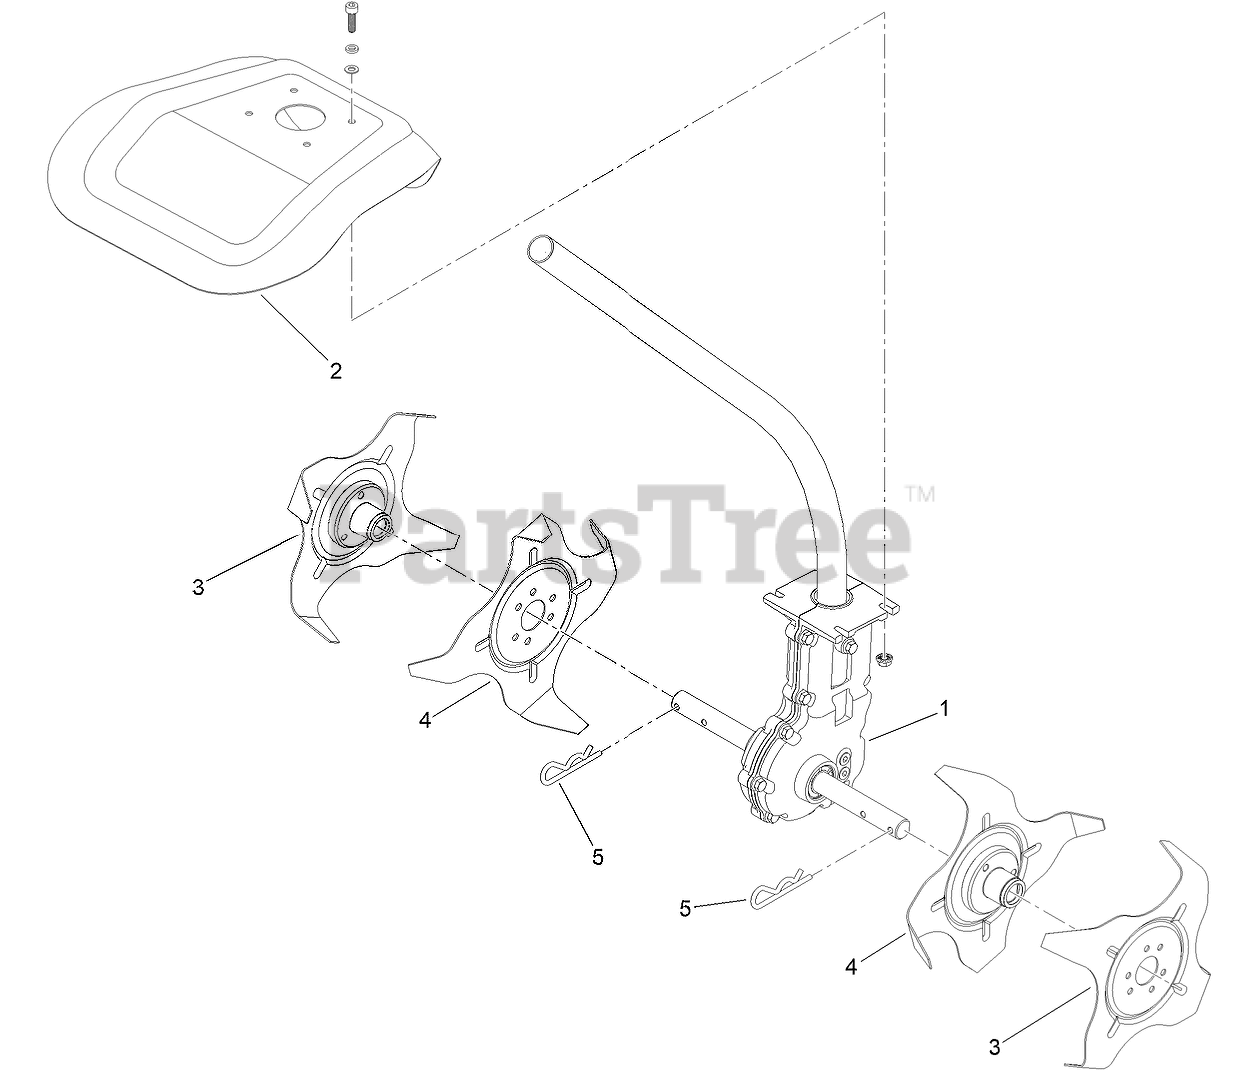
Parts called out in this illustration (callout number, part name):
1	GEAR BOX
2	AUGER COVER
3	BLADE SET (OUTER)
4	BLADE SET (INNER)
5	CLEVIS PIN SET (2)
